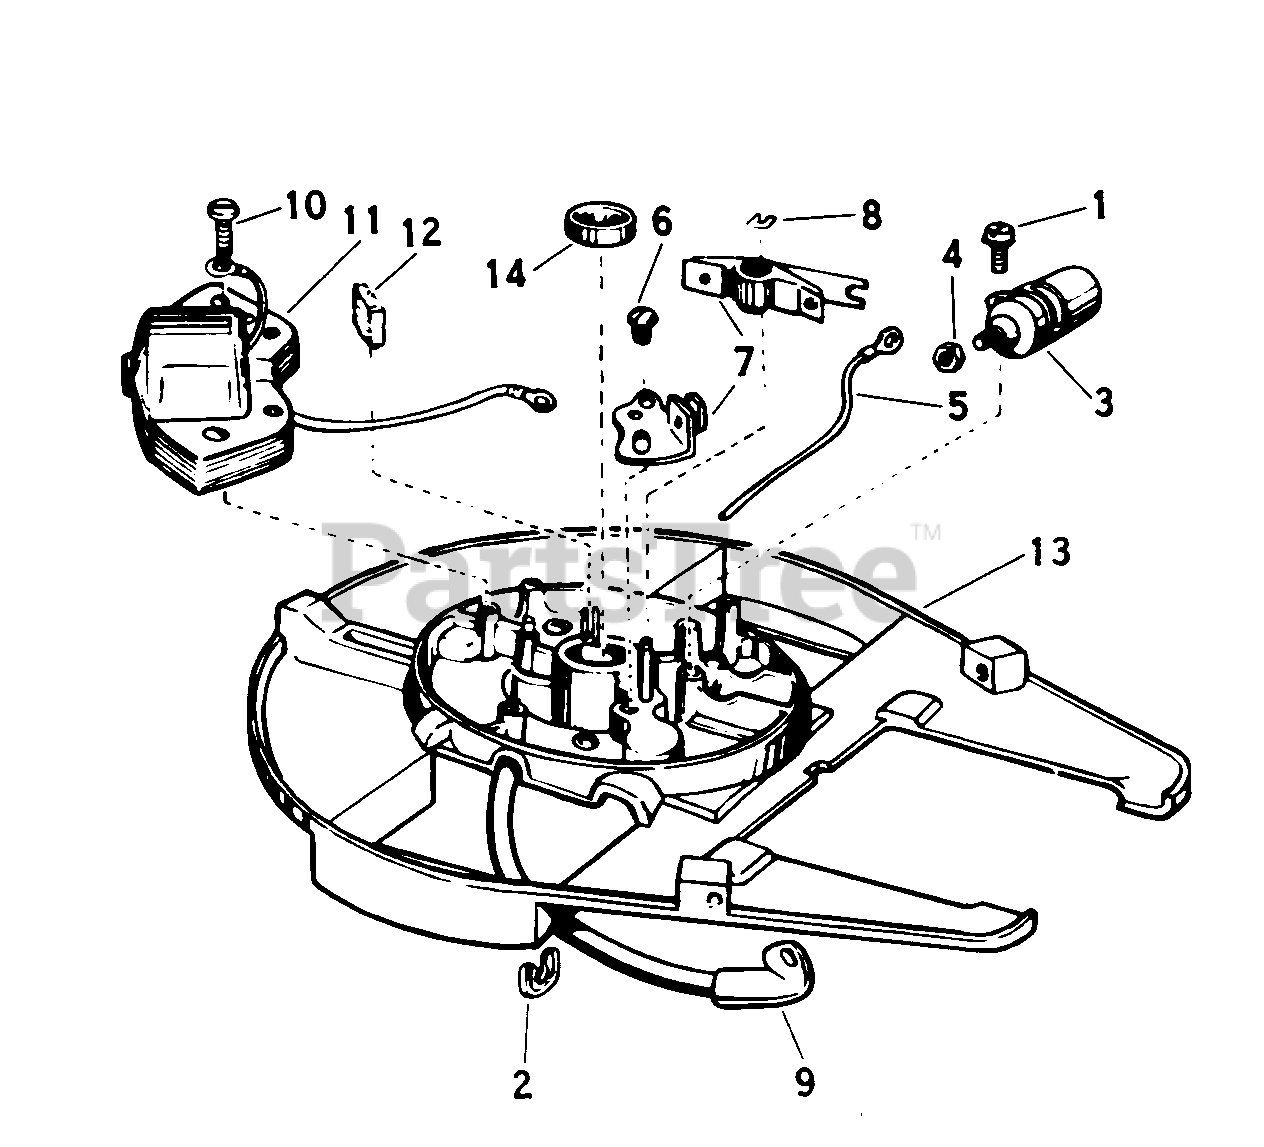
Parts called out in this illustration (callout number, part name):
1	Screw-Condenser Mounting
2	Clamp-High Tension Lead
3	Condenser Assembly
4	Nut-Condenser Terminal
5	Terminal and Lead Assembly
6	Screw-Breaker Base
7	Breaker Base and Arm Assy.
8	Spring Clip-Breaker Post
9	High Tension Lead Assembly
10	Screw-Lamination Mounting
11	Coil and Lamination Assembly
12	Oiler Wick
13	Armature Plate, Bearing, and Oil Seal Assembly
14	Oil Seal
